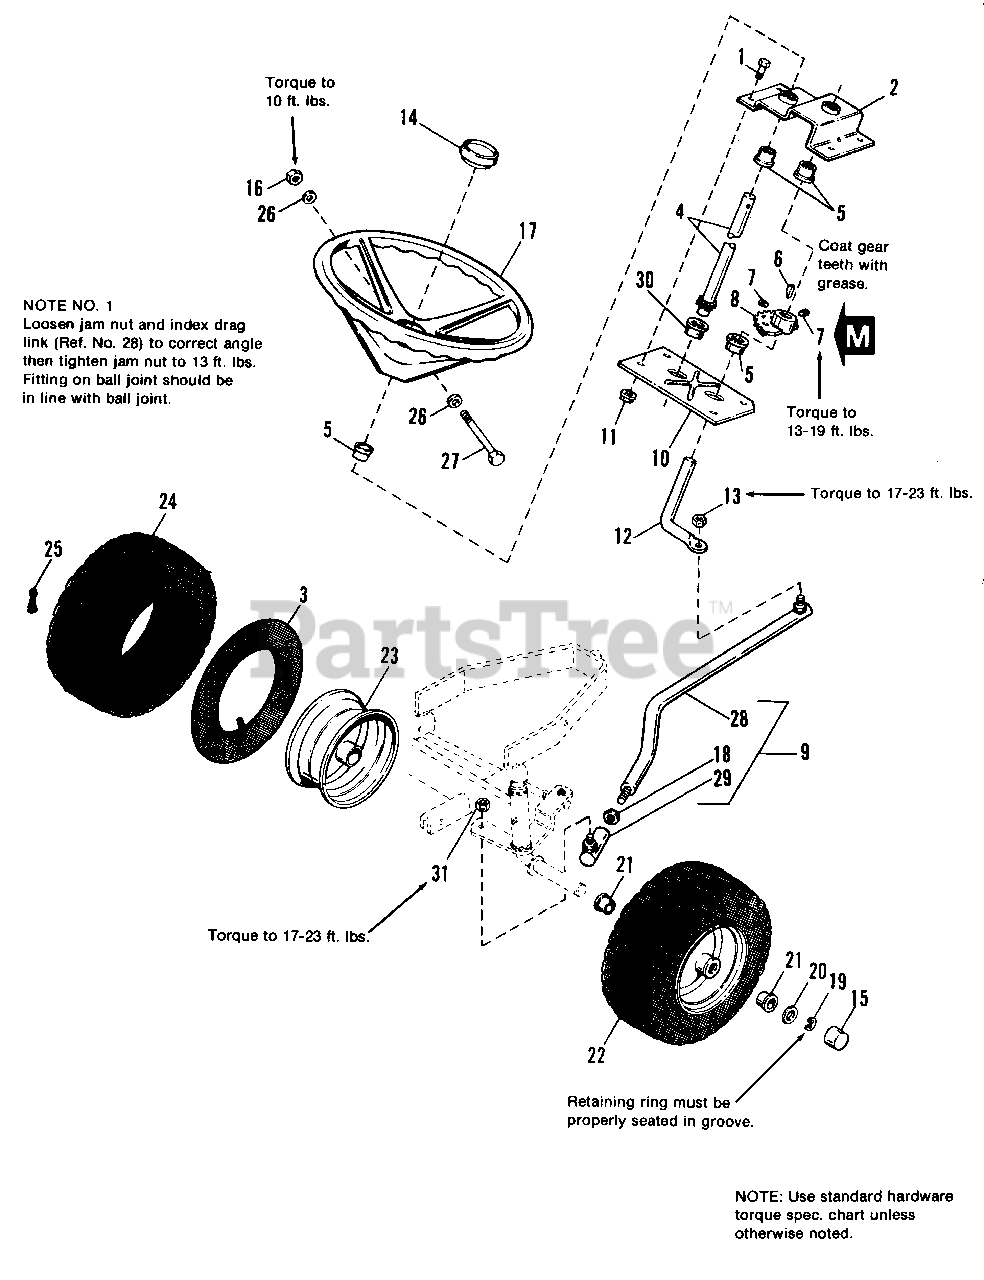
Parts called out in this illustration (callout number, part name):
1	CAPSCREW, 5/16-18 x 3/4
2	TOP PLATE, Steering
3	TUBE (For Service Only)
4	SHAFT ASSY., Steering
7	SETSCREW, 5/16-18 x 1/2, Gr. 8
8	GEAR, Steering
9	LINK ASSY., Drag (Includes Ref. Nos. 18, 28, & 29)
10	BASE PLATE, Steering
11	LOCKNUT, Flange, Whiz, 5/16-18
12	ROD, Steering
13	NUT, Special, 3/8-24
14	CAP, Steering Wheel
15	CAP, Hub, Threaded
16	LOCKNUT, Hex, 5/16-18
17	WHEEL, Steering
18	NUT, Jam, 1/2-20
19	"E" RING, Ext., 3/4
21	BEARING
22	WHEEL & TIRE ASSY., 15 x 6.00-6
23	WHEEL
24	TIRE (Carlisle), 15 x 6.00-6, Turf Mate
25	STEM, Valve
26	WASHER, Plain, 5/16
27	BOLT, Hex, 5/16-18 x 3-1/2
29	BALL JOINT ASSY.
31	NUT, Hex Centerlock, 1/2-20
